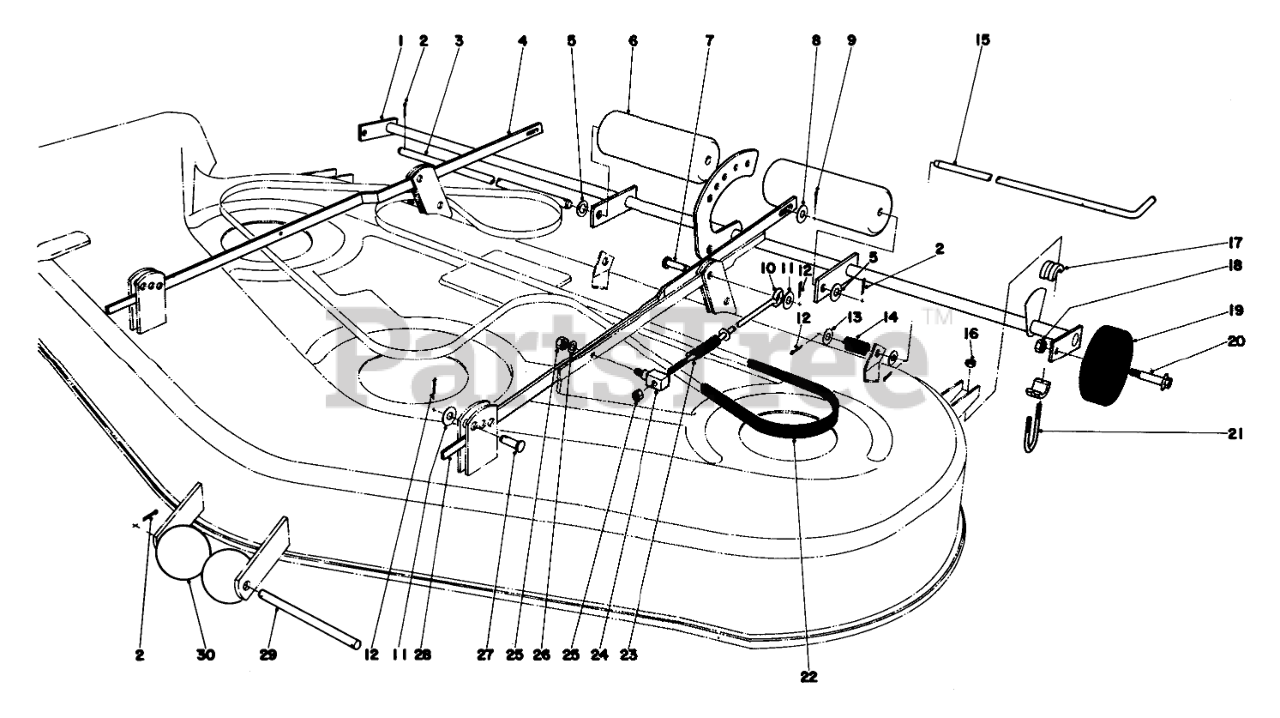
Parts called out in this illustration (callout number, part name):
1	Deck Wheel Shaft
2	PIN-COTTER
3	ROLLER SHAFT B
4	RR SCISSORS LNK B
5	WASHER-FLAT
6	ROLLER-DECK
7	PIN-CLEVIS
8	WASHER-FLAT
9	PIN-COTTER
11	WASHER-FLAT
12	PIN-COTTER
13	WASHER-FLAT
14	Spring
15	WHEEL LATCH ROD B
16	NUT-LOCK, CONE
17	BEARING DECK SH WHEEL
18	Nut
19	DECK WHEEL
21	U-BOLT
22	V-BELT, DECK
23	DECK IDLER SPRING
24	PIN SCISSORS LINK
25	NUT-LOCK, CONE
26	WASHER-PLAIN
27	PIN-CLEVIS
28	Scissors Link Rear L.H.
29	ROLLER SHAFT
30	ROLLER
